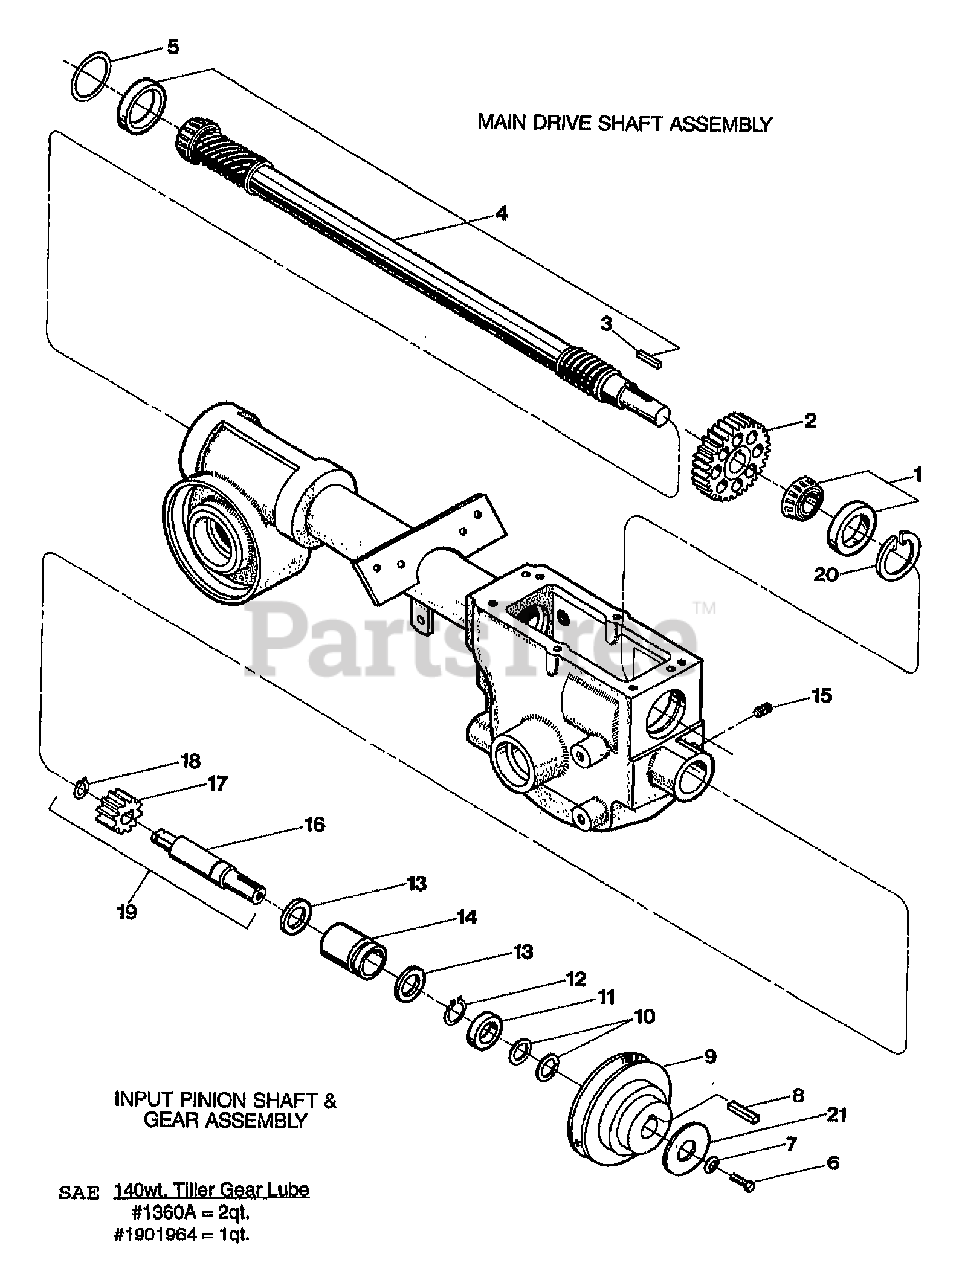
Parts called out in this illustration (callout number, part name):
1	KIT-BRG CONE&RACE-DRIVESHAFT (FRONT OF DRIVE SHAFT)
2	GEAR-SPUR 30 TEETH
3	KEY-.188 SQX1.0
4	KIT-DRIVESHAFT
5	SHIM-1.75X1.5X.01
5	SHIM-1.75X1.5X.03
5	SHIM-1.75X1.5X.005
6	SCR-HH 5/16-24X.75 G5 ZP
7	WASHER-.827X.331X.098
8	KEY-.188 SQ1.0
9	PULLEY-TRANS MACH
10	WASHER # .875 X .65 X .06
11	SEAL-PINION SHAFT PT/85030/00
12	RING-RETAIN EXT .707 ID (SNAP RING)
13	WASHER-1.022X.752X .059
14	BUSHING-1.24X.75X1.8 GRVD
15	SCR-SS 5/16-18X.375
16	SHAFT-PINION(P-V)
17	GEAR-PINION P/M
18	RING-BOWED EXT .461 ID
19	PINION W/GEAR&SNAP RING
20	RING-RETAINING 5000-181
21	WASHER-2.5X.316X.06
